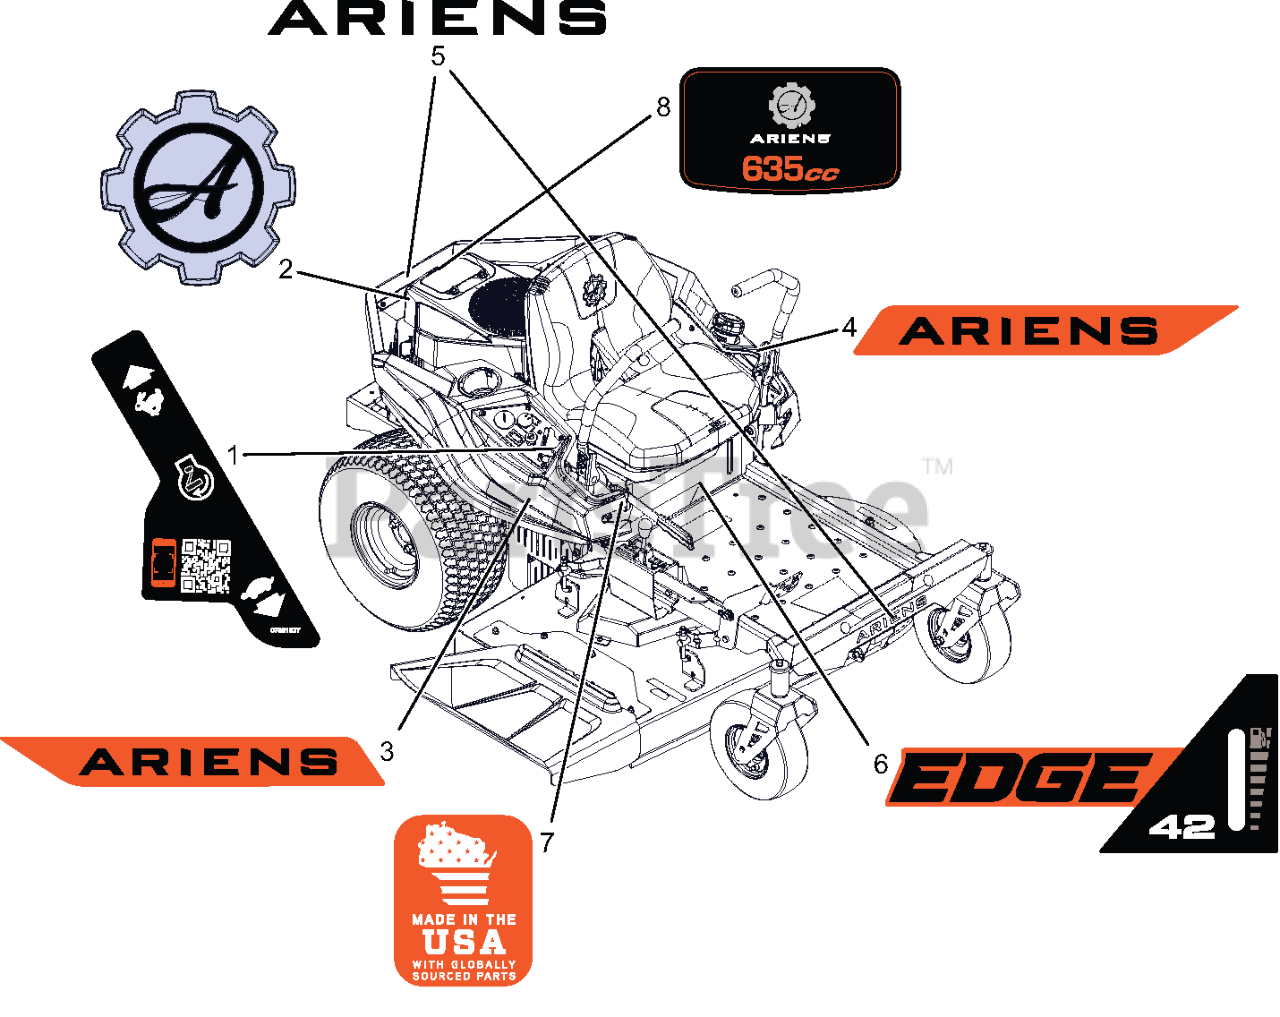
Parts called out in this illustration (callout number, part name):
1	DECAL- TROTTLE CONTROL
2	DECAL- ARIENS GEAR BADGE
3	DECAL- ARIENS (FENDER RH)
4	DECAL- ARIENS (FENDER LH)
5	DECAL- ARIENS 9.625" BLACK
6	DECAL- EDGE 42 KICKPLATE
7	DECAL- MADE IN USA
8	DECAL, ARIENS 653CC
